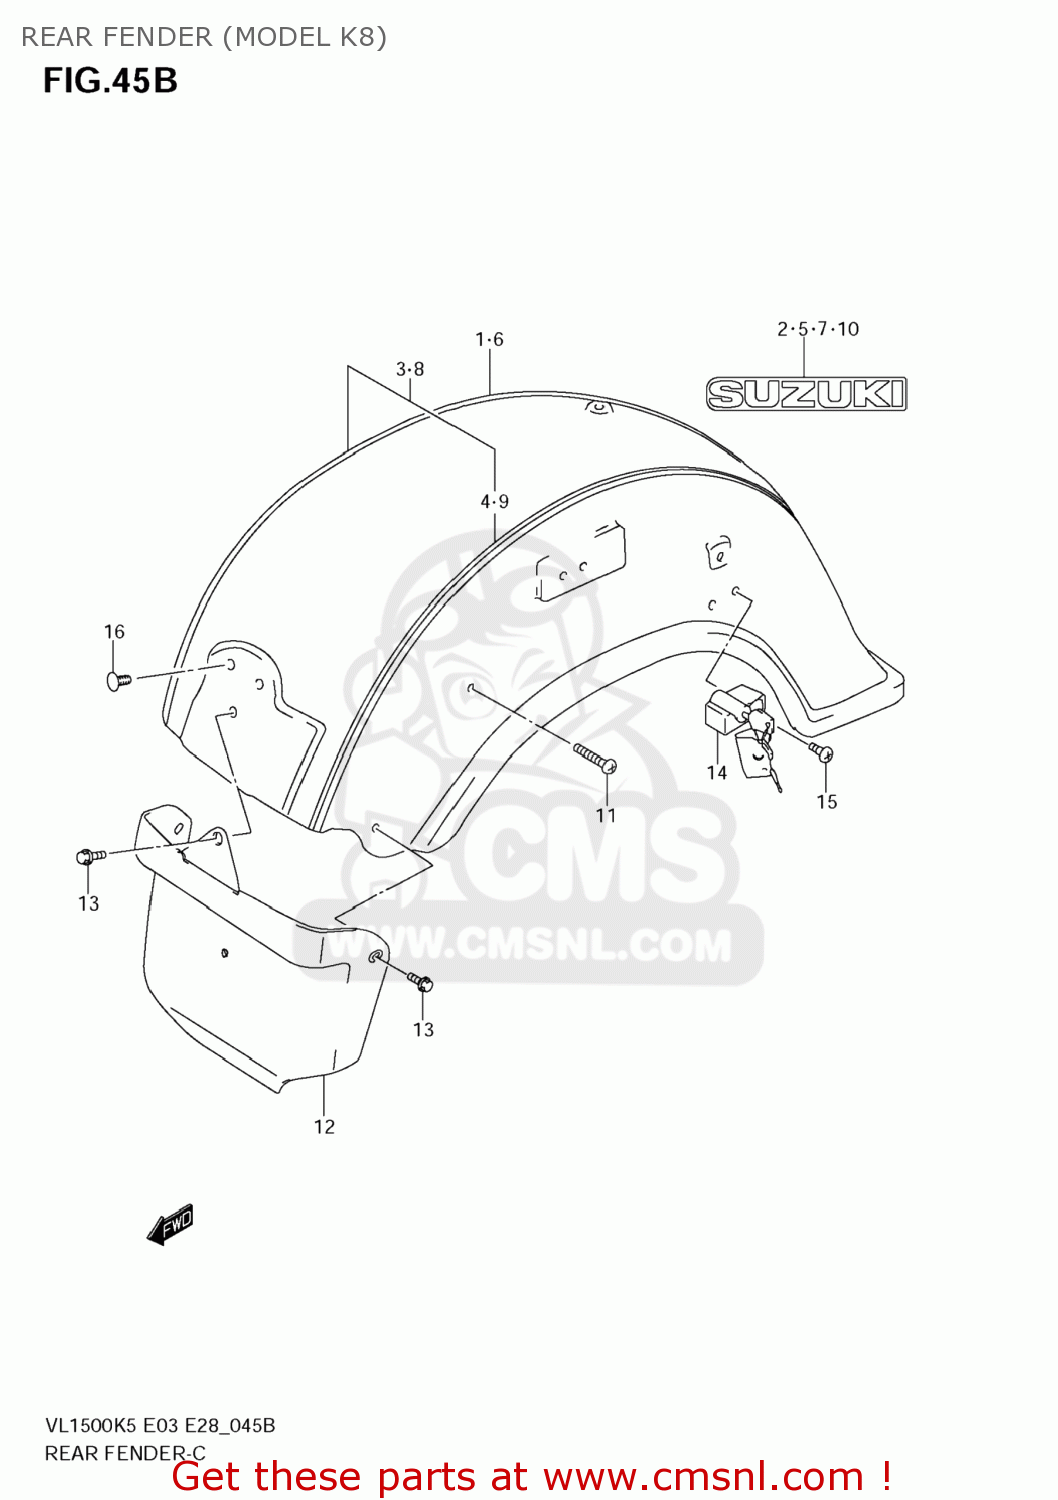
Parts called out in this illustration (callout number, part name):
1	FENDER ASSY,RR
2	EMBLEM,SUZUKI
3	FENDER ASSY,RR
4	TAPE SET,RR FENDER
5	EMBLEM,SUZUKI
6	FENDER ASSY,RR
7	EMBLEM,SUZUKI
8	FENDER ASSY,RR
9	TAPE SET,RR FENDER
10	EMBLEM,SUZUKI
11	BOLT(8X37)
12	BOLT(8X37)
13	BOLT(6X16)
14	LOCK SET,HELMET
15	SCREW(6X14)
16	CAP(OD:12)
